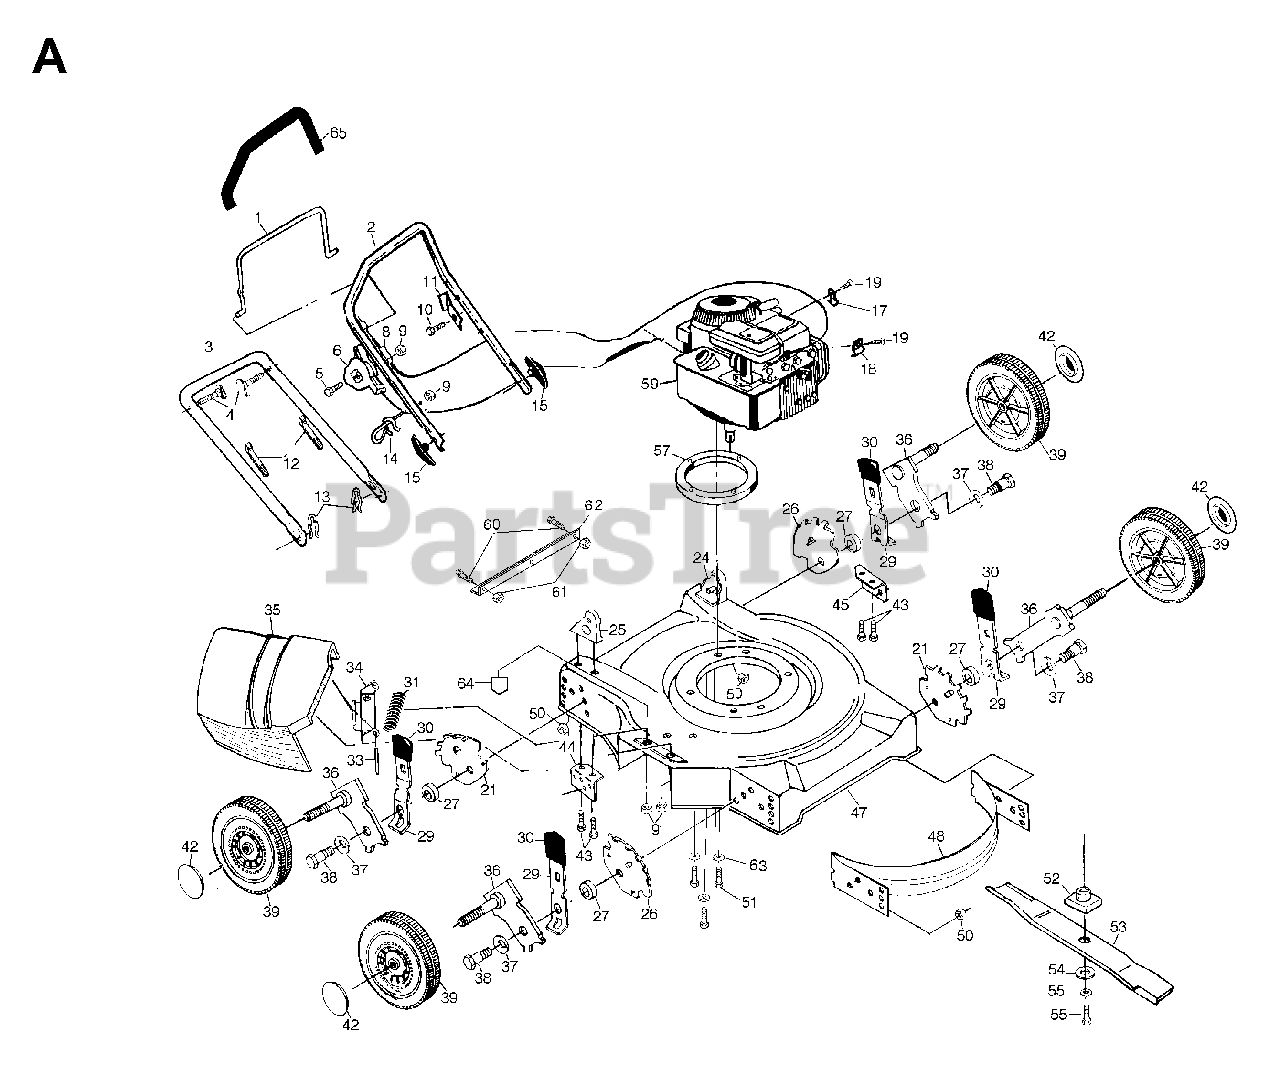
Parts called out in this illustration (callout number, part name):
1	CONTROL BAR/BLACK
4	HANDLE BOLT
6	THROTTLE CONTROL
8	ENGINE ZONE CONTROL CABLE
9	NUT
10	TAPPING SCREW
11	BRACKET UPSTOP
13	HAIRPIN COTTER
14	ROPE GUIDE
15	HANDLE KNOB
17	CABLE CLAMP(ENGINE)
18	GUIDE CLIP PM
19	SCREW.HEX.HEAD.WASHER.10-16
21	BRACKET.WHL.ADJ.L
24	HDLE BRKT ASSY LH
25	HDLE BRKT ASSY RH
26	BRACKET.WHL.ADJ.R
27	RP SPACER HT ADJ
29	SELECTOR SPRING
31	SPRING PM
33	ROD.HINGE.COMBI-C
34	BRACKET PM
36	AXLE, REAR
37	BELLEVILLE WASHER
38	BOLT
43	SELF-TAPPING SCREW 5/16-18X3/4
50	LOCKNUT PM
52	BLADE ADAPTOR
53	BLADE.20.MULCH.(50DK,6020MD)
54	WASHER,HARDEN
55	LOCKWASHER
56	SCREW, HEX HD 3/8-24 X 1-3/8
64	HEX FLANGE LOCKNT
64	DECAL MOWER CUT/FINGER
